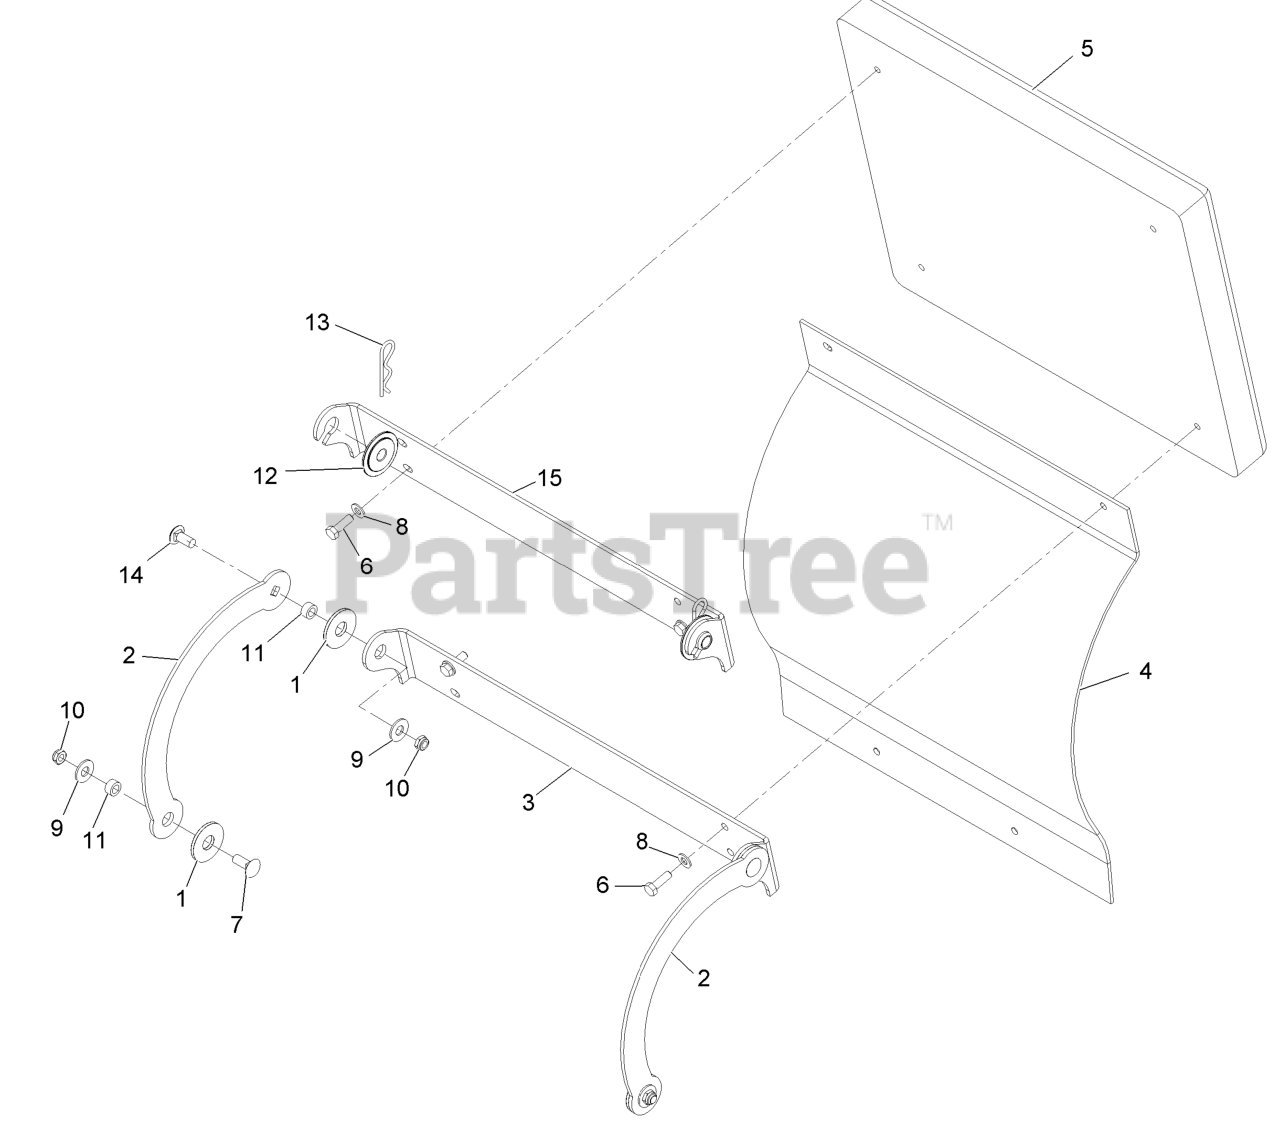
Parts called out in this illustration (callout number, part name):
1	WASHER-FRICTION, COMPOSIT
3	HINGE-PAD
5	PAD,GREY CUSHION
6	SCREW-HH, THREAD LOCKING
7	BOLT-CARR
8	WASHER-PLAIN
9	WASHER-FLAT
11	SPACER
12	SLIDE-BUSHING
13	PIN-HAIR
14	SCREW-CARR
15	HINGE-PAD
